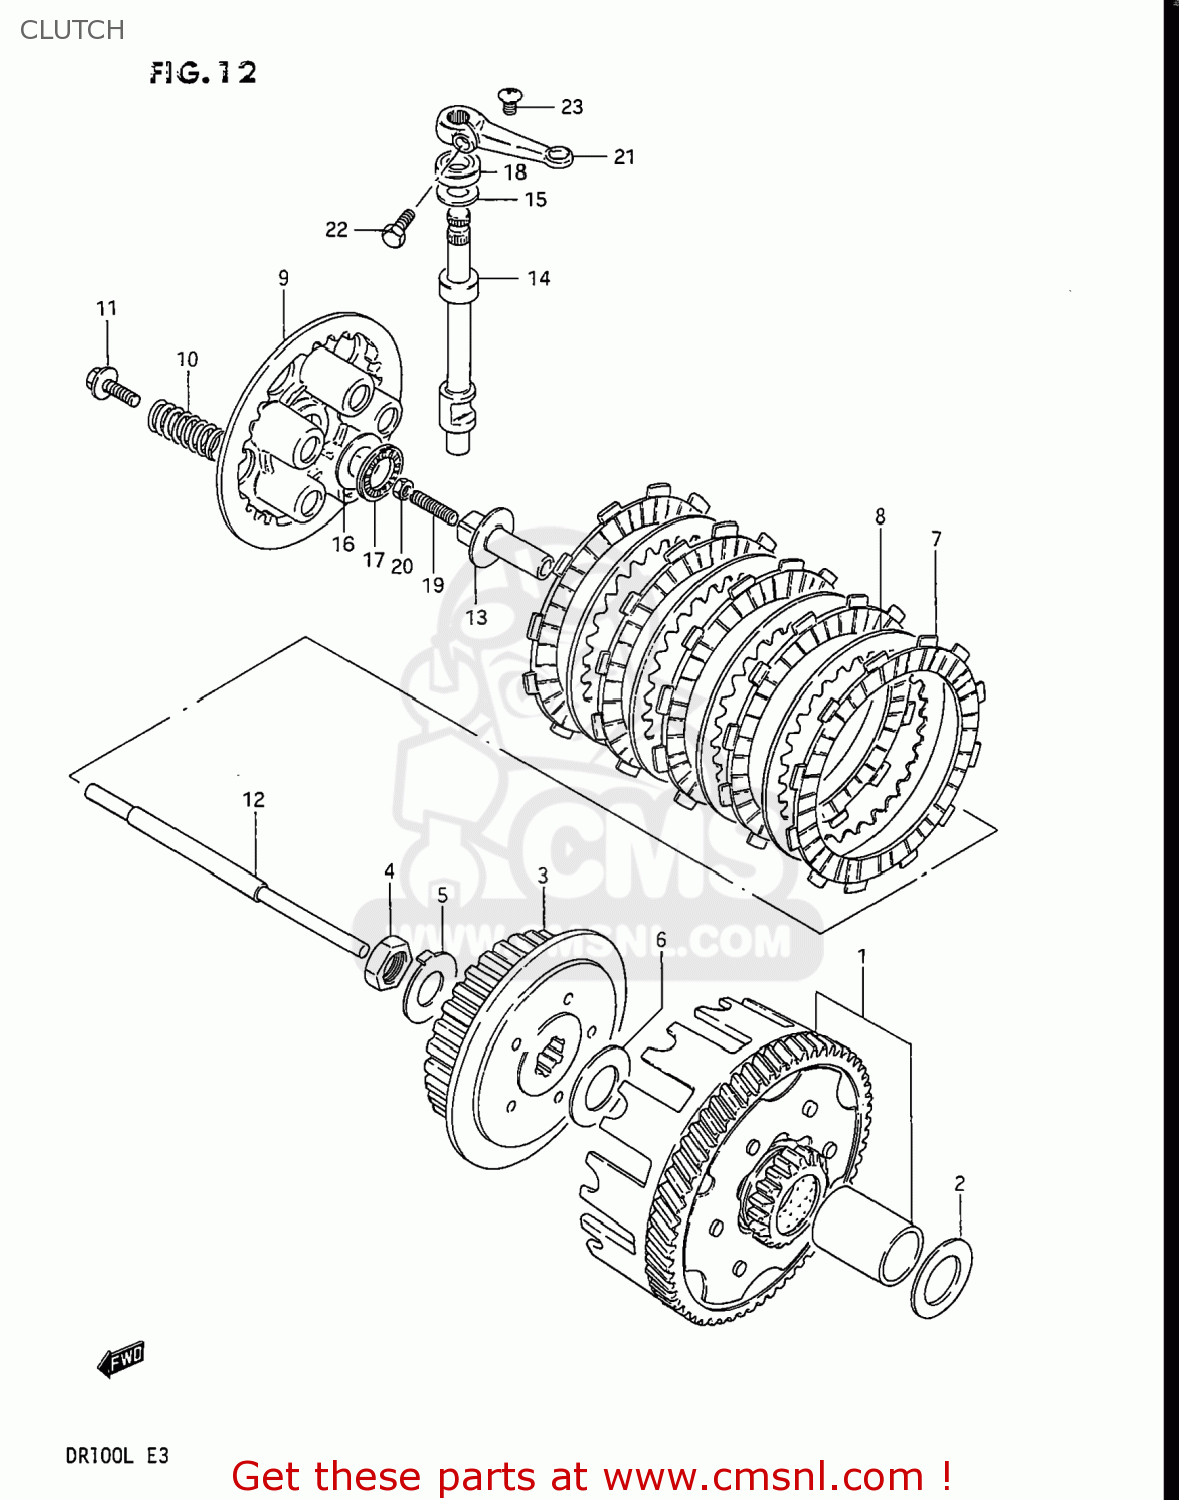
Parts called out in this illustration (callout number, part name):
1	GEAR ASSEMBLY,PRIMARY DRIVE
2	WASHER
3	HUB,CLUTCH SLEEVE
4	NUT
5	WASHER
6	WASHER
7	PLATE,CLUTCH DRIVE (NAS)
8	PLATE,CLUTCH DRIVEN (NAS)
9	PLATE,CLUTCH PRESSURE
10	SPRING
11	BOLT 5X16
12	ROD,CLUTCH PUSH
13	PIECE,CLUTCH PUSH
14	CAMSHAFT,CLUTCH RELEASE
15	WASHER,THRUST
16	WASHER
17	BEARING(15X28X2)
18	OIL SEAL
19	SCREW(6X25)
20	NUT 6MM
21	ARM,CLUTCH RELEASE
22	BOLT
23	SCREW
